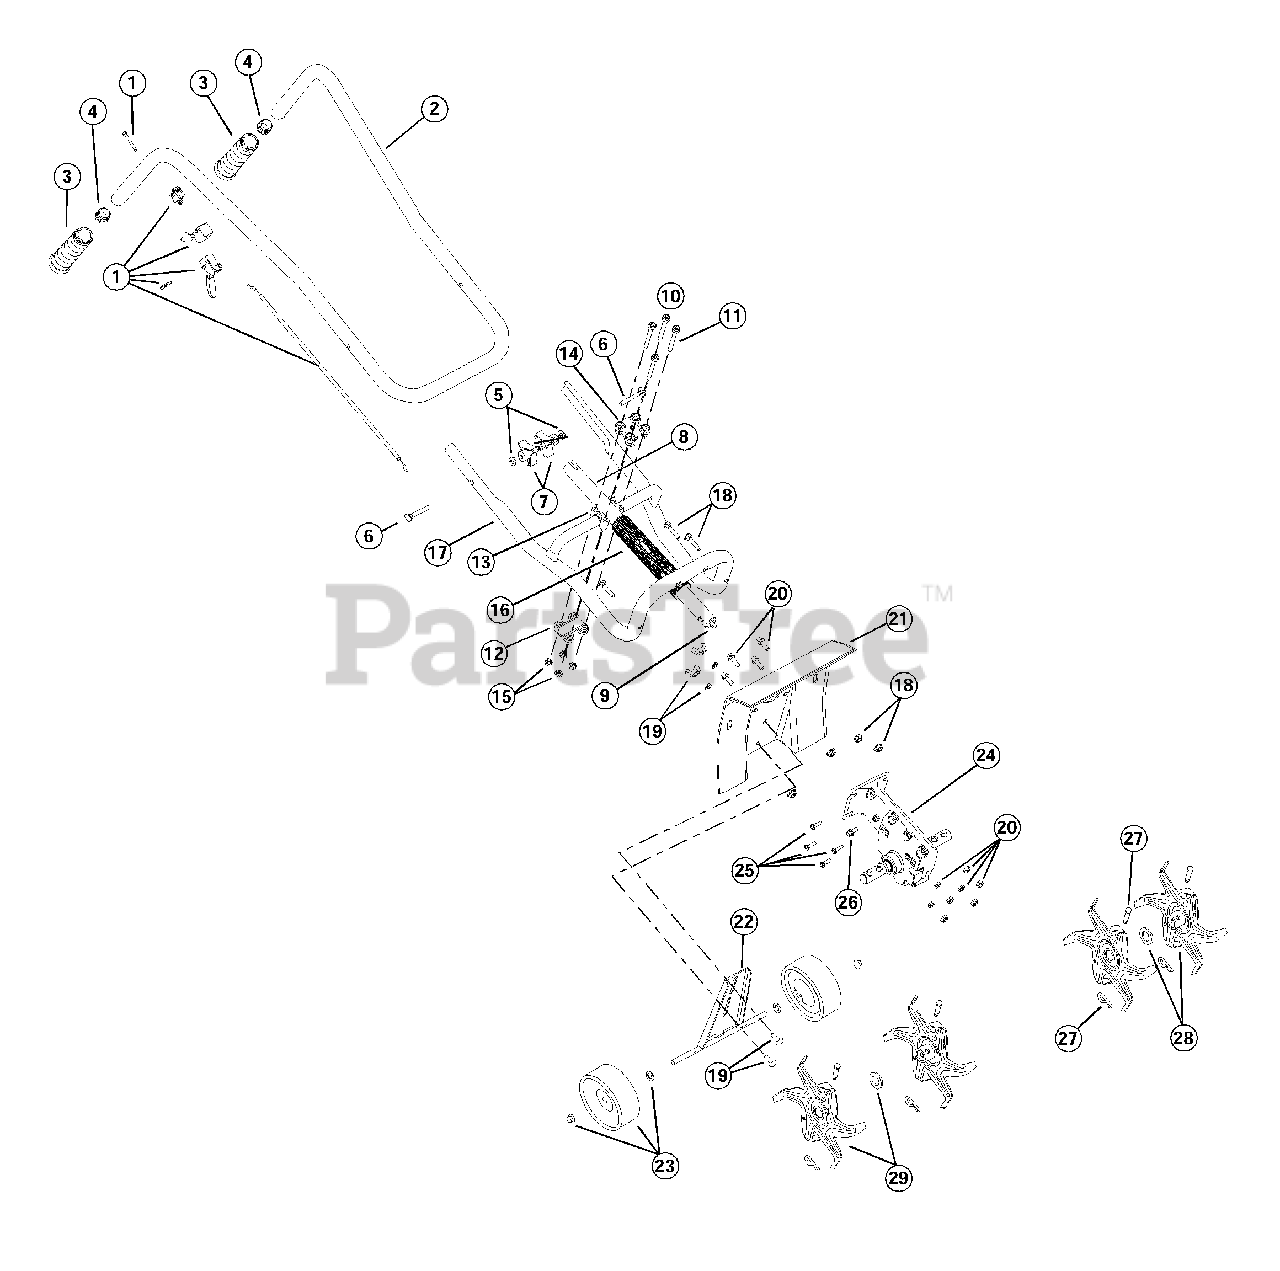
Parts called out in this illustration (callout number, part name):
1	Throttle Trigger and Cable Assembly
2	Handle Bar Assembly, Upper
4	Tube Closure
5	Washer
7	Knob, 3 prong
8	Drive Shaft Housing Assembly
9	Flexible Drive Shaft
10	Handle Bracket Assembly
12	Upper Handle Clamp
13	Middle Handle Clamp
14	Lower Handle Clamp
17	Lower Handle Bar
18	Hardware, Handle Bar Mounting (lower)
19	Wheel Bracket Mounting Hardware
20	Guard Mounting Hardware
22	Wheel Bracket Assembly
23	Wheel Assembly
24	Gear Box Assembly
26	Sleeve Retainer Bolt
27	Tine Fastener Assembly
28	Tine Assembly (Left Outer or Right Inner)
29	Tine Assembly (Left Inner or Right Outer)
